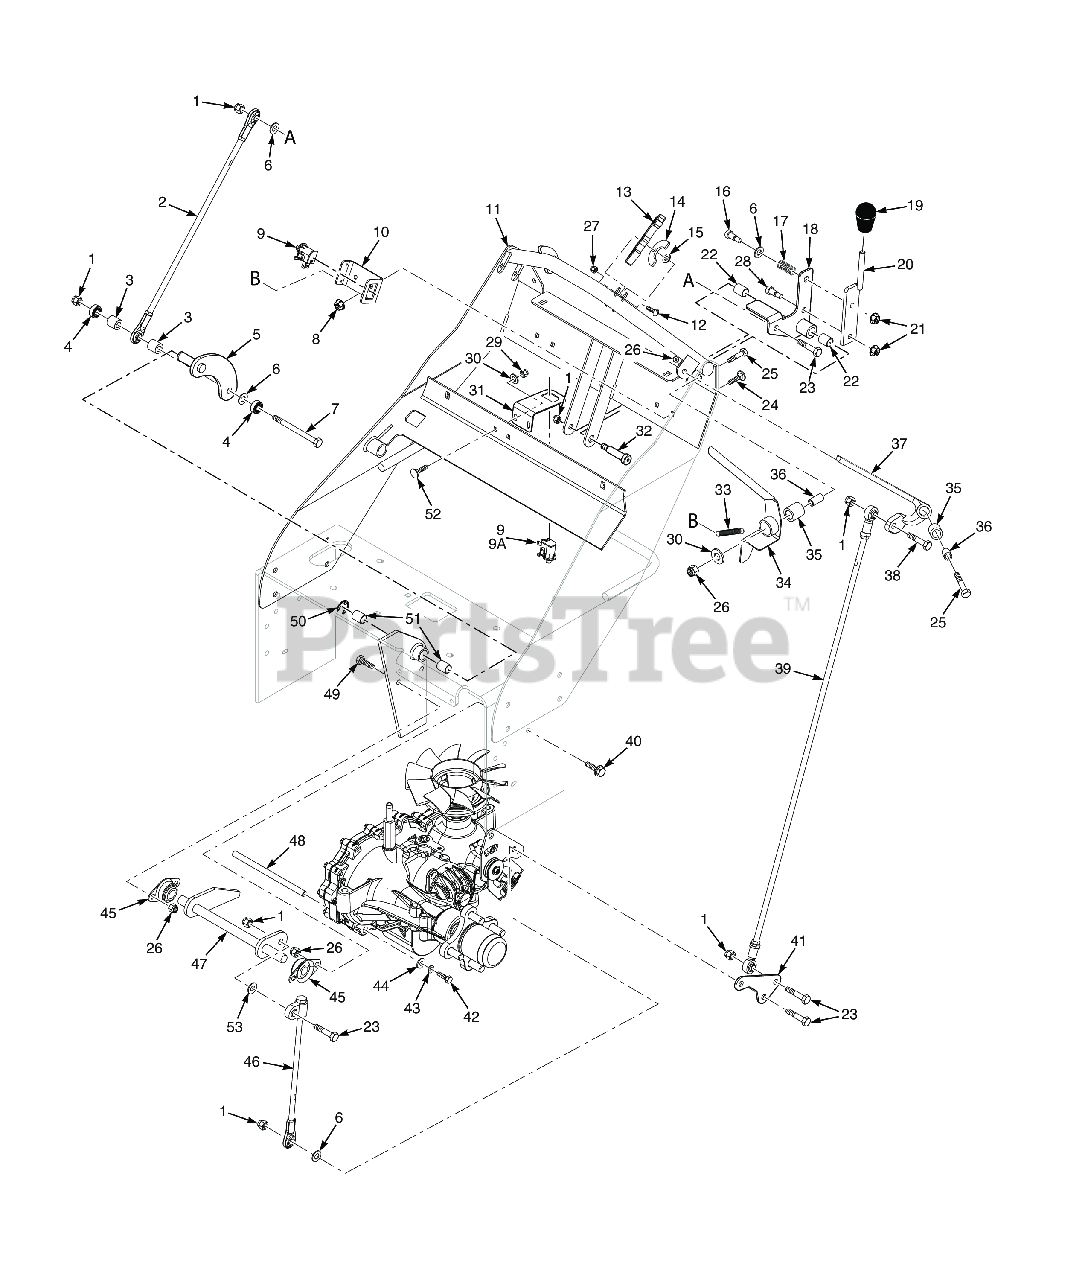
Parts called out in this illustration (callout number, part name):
1	HEX NUT, ELASTIC STOP LOCK, 3/8-16
2	Linkage, Speed Control
3	Spacer, Idler Pulley - SFZ52
4	Bearing
5	Neutral Plate Weldment
6	Flatwasher, 3/8 (.406 x .812 x .065)
7	Bolt, Hex Head, 3/8-16 x 3-1/2"
8	NUT, 1/4-20 SERRATED FLANGE HEX HEAD
9	SWITCH, NEUTRAL INTERLOCK
9A	Switch, Double Pole - Plunger
10	Bracket, Operator Presence Switch
11	Handle Assy, W/Decals
12	Machine Screw, #10-32 x 1-1/4", Pan Head
13	LATCH, THUMB
14	Plate, Anti-Friction
15	Washer, 1/4" Curved Spring
16	Bolt, Shoulder 3/8 x 1"
17	Spring, Speed Control Slide
18	Neutral Handle Assy
19	Knob, Soft Touch
20	Handle Weldment, Speed Control
21	Nut, Serrated Flange 5/16-18 (Right Front Engine Mounting, Briggs and Kohler Only)
22	Bearing, Plastic 1/2" I.D.
23	Bolt, Hex Head, 3/8-16 x 1-1/2"
24	Bolt, Carriage, 1/4-20 x 1-1/4"
25	Bolt, Hex Head 5/16-18 x 1-1/2" - Front
26	HEX NUT, ELASTIC STOP LOCK, 5/16-18
27	HEX NUT, ELASTIC STOP LOCK # 10-32
28	Bolt, Shoulder 3/8 x .375"
29	HEX, NUT, ELASTIC STOP LOCK, 1/4-20
30	Flatwasher, 5/16-.375 x .875 x .083 (35BV & 37BV-EFI)
31	Bracket, Neutral Switch (Manual Start)
31	Bracket, Neutral Switch (Electric Start Only)
32	Bolt, Shoulder 1/2 x 2"
33	Spring, Operator Presence
34	Handle, Op. Presence-LH
34	HANDLE ASSY, OPC - RH
35	Bearing
36	Sleeve, Handle Pivot
37	Handle Assembly-LH
37	Handle Assembly-RH
38	Bolt, Hex Head 3/8-16 x 1-3/4" (Kohler EFI)
39	Linkage, Steering
40	Capscrew, 5/16-18 x .75 Serrated Flange Hex Head
41	Bracket, Transaxle Control
42	Capscrew, Hex Head 3/8-16 x 2.0"
43	Lockwasher, 3/8" Spring, Kawasaki FX / FS
44	Flatwasher, 3/8" Special (.391 x .938 x .105)
45	Bearing, Self Aligning - 5/8 I.D.
46	Linkage, Pump
47	Weldment, Bellcrank-LH
47	Weldment, Bellcrank-RH
48	Spacer, Axles
49	Bolt, Heax Head 5/16-18 x 1" (48V / 52V)
50	RETAINING RING, 5/8" EXTERNAL "E"
51	Bearing
52	Serr. Fl. Hex Head CPSCR, 1/4-20 x 3/4"
53	Flatwasher, 3/8 (.391 x .938 x .105 HD) Grade 8
